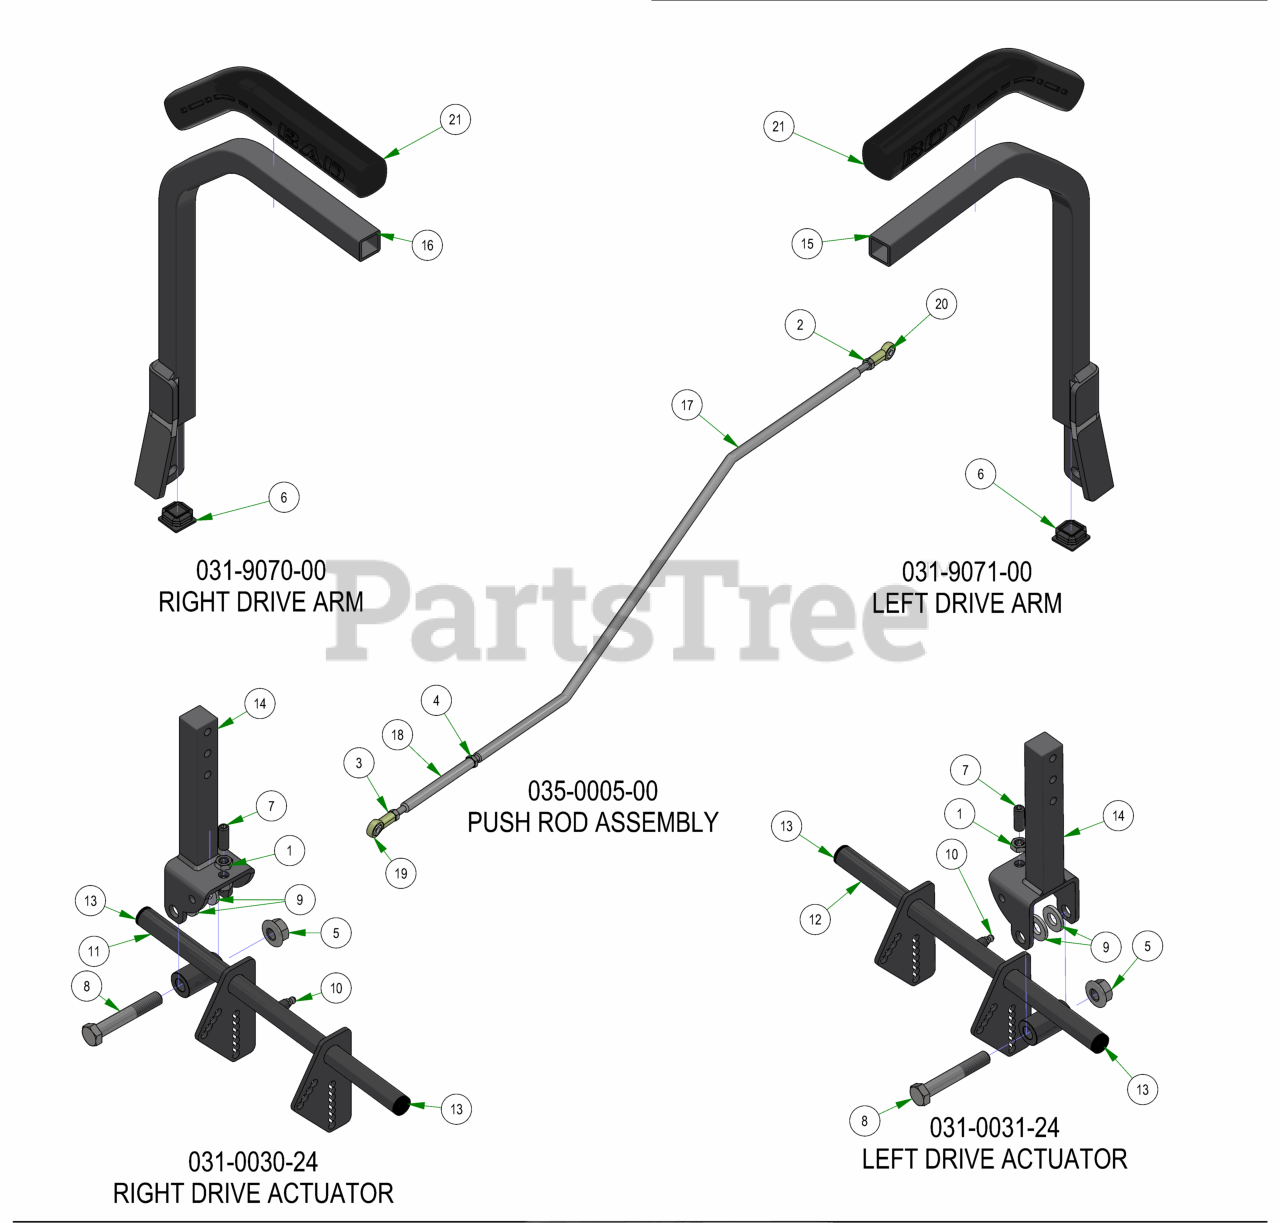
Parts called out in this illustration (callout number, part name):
1	3/8-16 Half Jam Nut
2	5/16 RH Nut
3	5/16 LH Nut
4	3/8-24 HEX NUT ZINC YELLOW
5	1/2-13 NYLON INSERT FLANGE LOCKNUT ZINC
6	9565K52_Polyethylene Square Plug
7	3/8-16 X 1 SOCKET SET SCREW (CUP POINT) PLAIN
8	1/2-13 X 3 HEX CAP SCREW (GR.5) ZINC
9	.505 ID X 1.000 OD X .125 THICK FLAT WASHER NYLON
10	1/4 DRIVE-TYPE STRAIGHT GREASE FITTING ZINC YELLOW)
11	2019 Drive Arm Actuator right - Weldment
12	2019 Drive Arm Actuator left - Weldment
13	2019 Drive Arm Bushing
14	R Series Square Drive Arm Pivot
15	R Series Square Drive Arm LH Weldment
16	R Series Square Drive Arm RH Weldment
17	2019 Renegade Push Rod
18	2019 Renegade Push Rod Adjuster
19	Spherical Rod End - Outlaw
20	Spherical Rod End - Outlaw
21	R-Series Square Drive Grip
